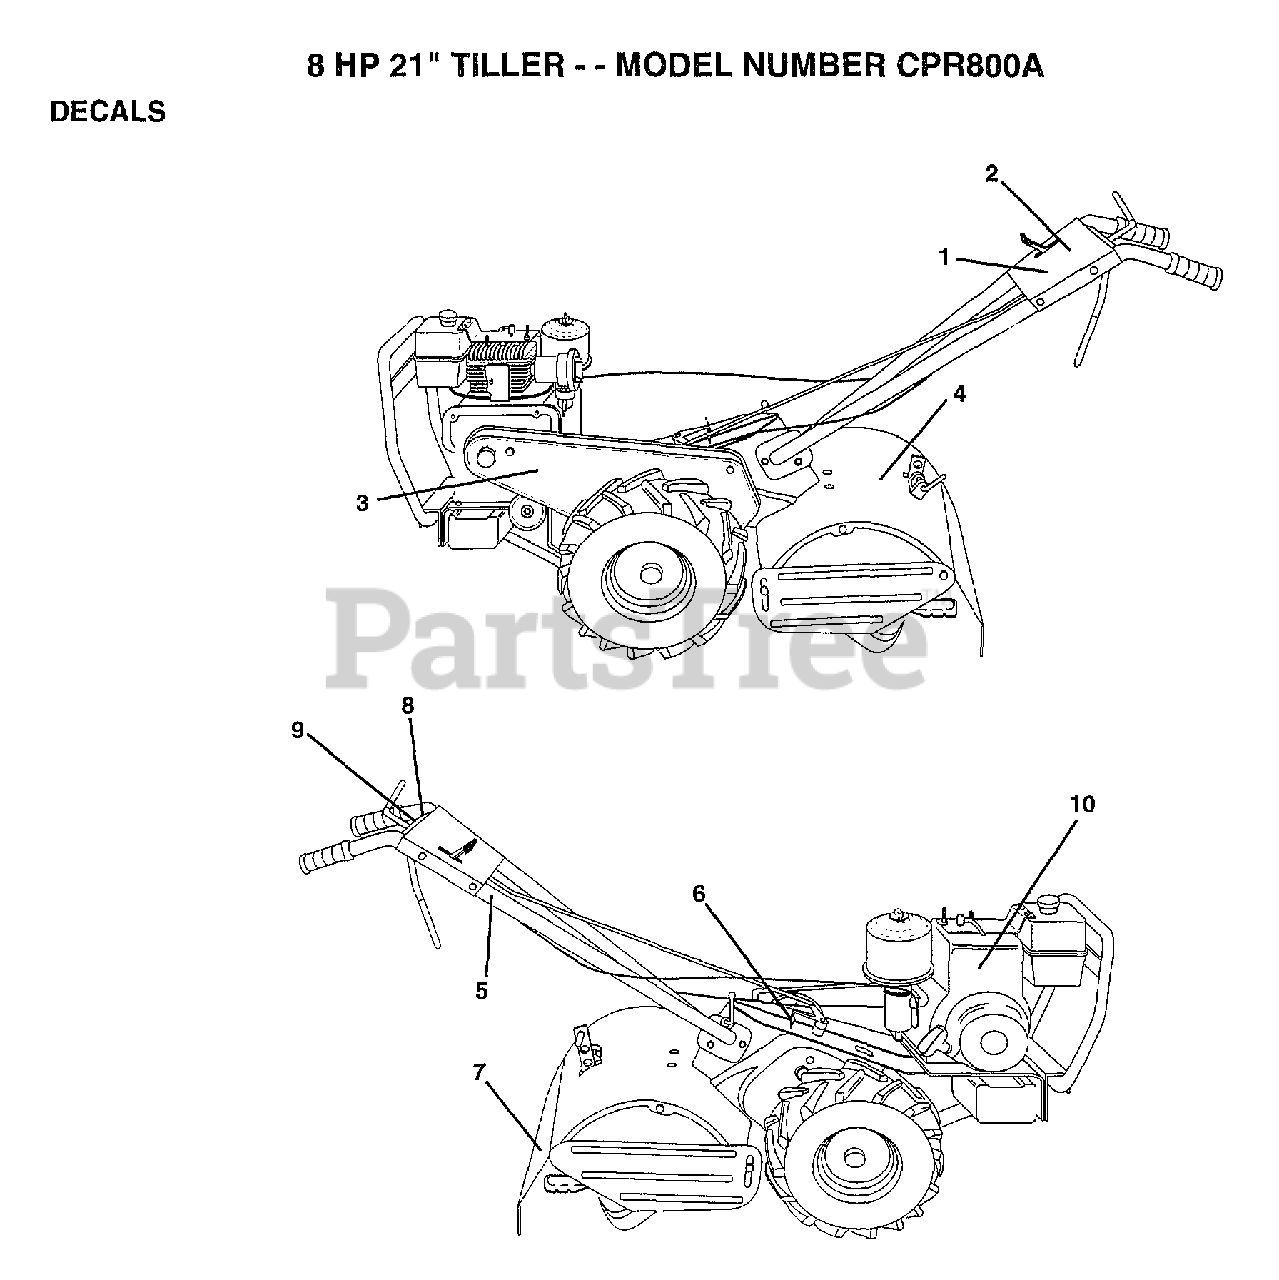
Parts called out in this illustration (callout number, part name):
1	DECAL.PNL.CNTRL.
2	DECAL, PANEL CONTROL
3	DECAL.BELT.GRD.CP
4	DECAL, LOGO
5	DECAL TI
6	DECAL.SHIFT.IND.
7	DECAL TI
10	DECAL, BRIGGS & STRATTON
